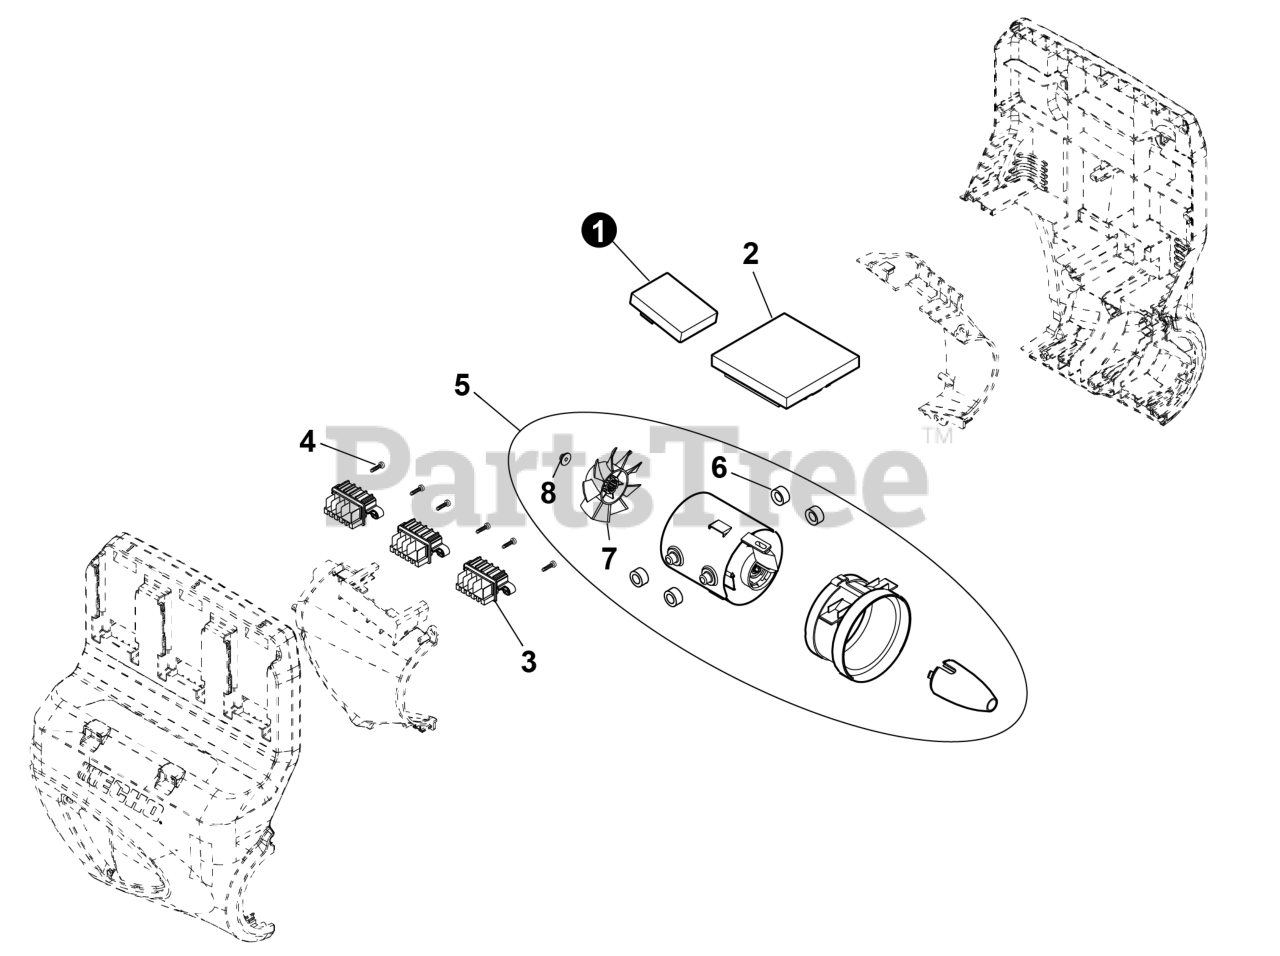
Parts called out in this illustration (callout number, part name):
3	BLOCK,TERMINAL
5	MOTOR ASSEMBLY
6	DAMPNER
